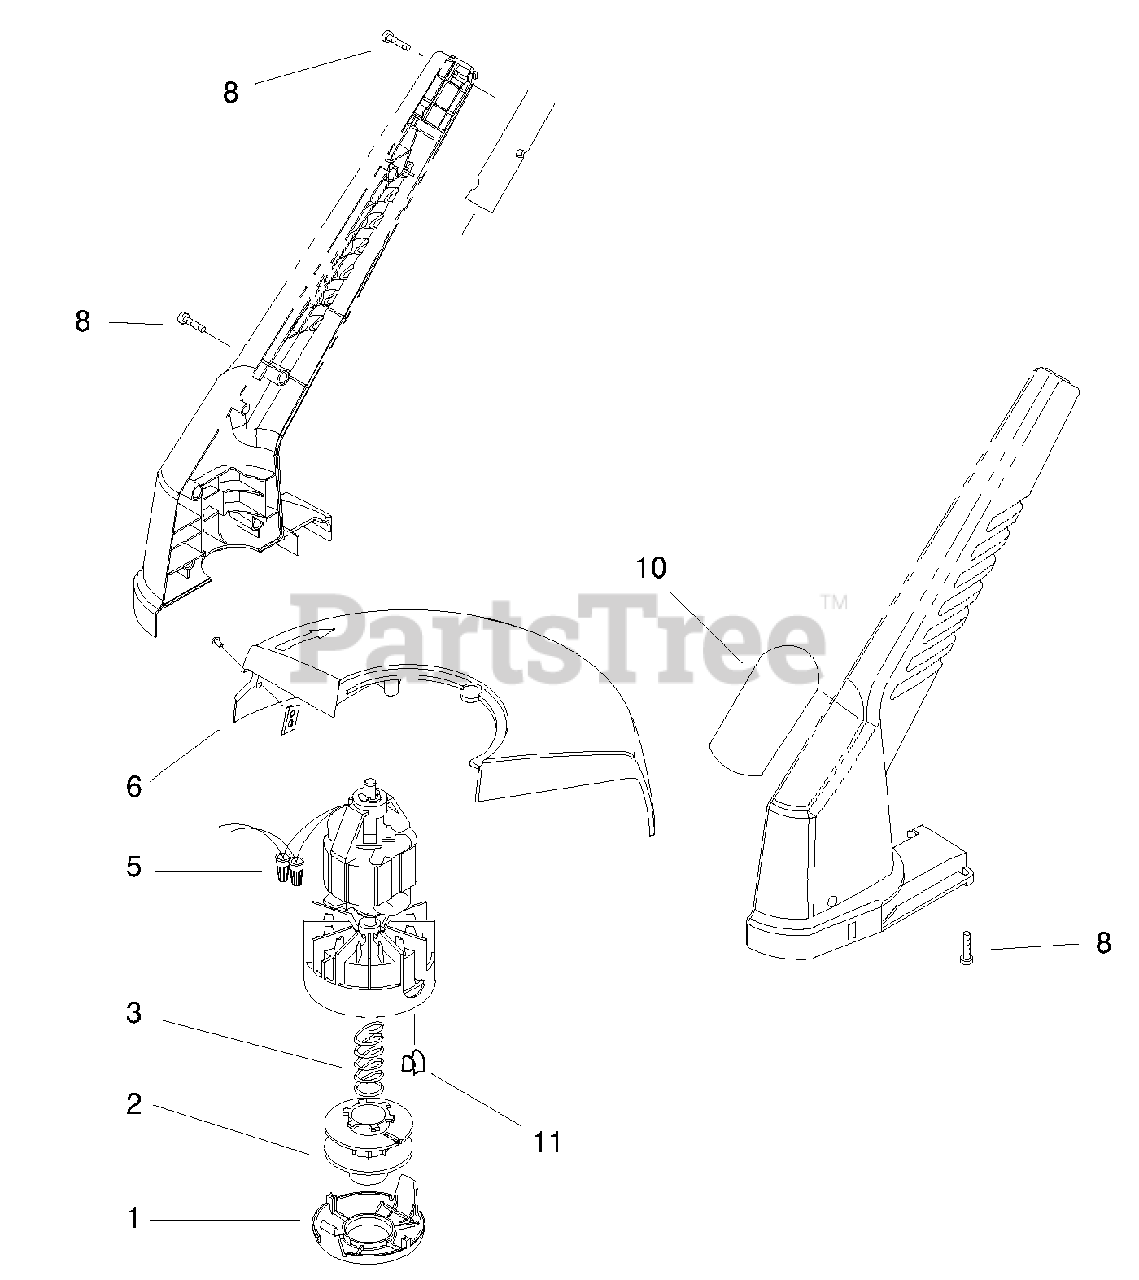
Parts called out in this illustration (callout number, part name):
2	SPOOL - LARGE
3	SPRING - COMPRESSION
5	CONNECTOR-WIRE NUT
6	SHIELD ASM-15"(SERVICE)
8	SCREW-PPH
10	DECAL-15" TRIM 'N EDGE
